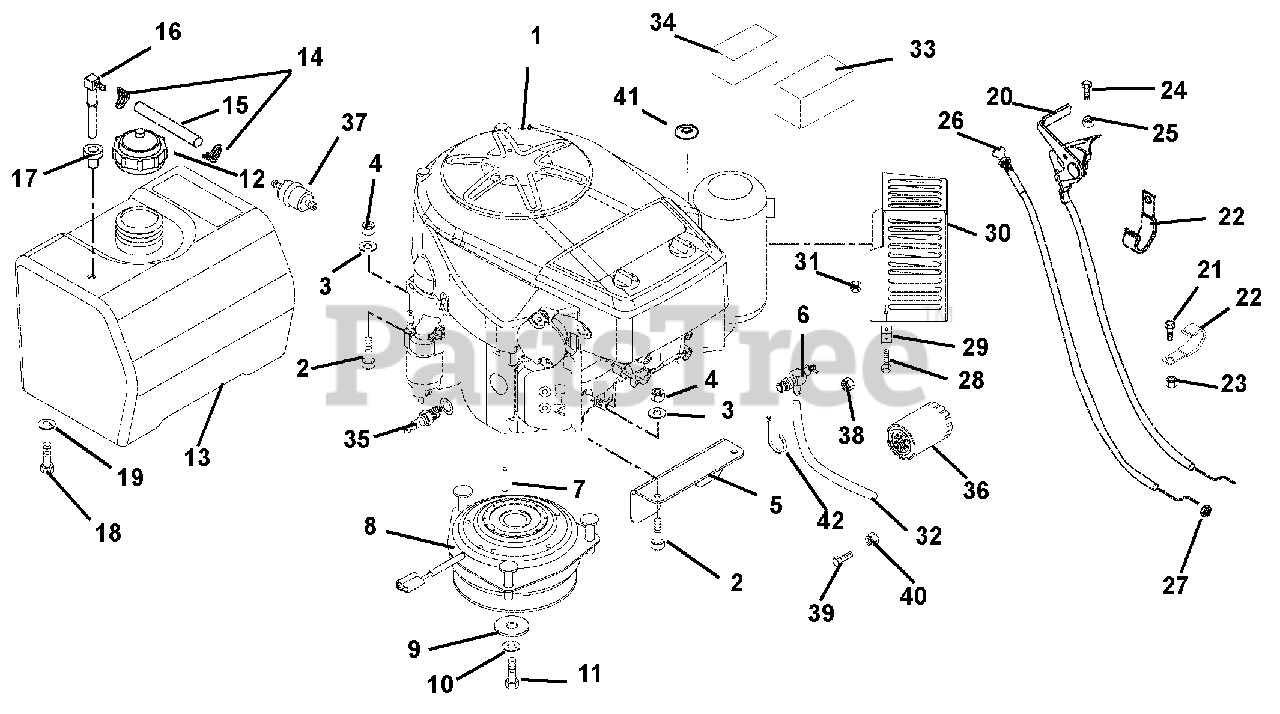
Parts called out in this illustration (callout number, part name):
1	Engine, 17 HP Kawasaki (108, 109, 117)
2	Bolt-Hex .31-18 x 1.75 Grade 5
3	Washer-Locking .31 x .078 Regular
4	Nut-Hex .31-18
5	Bracket, Clutch
6	Valve, Oil Drain
7	Key-Square .25 x 1.25 x 25 SAE 8630 OR SAE 1035
8	Clutch, Electric
9	Washer-Flat-Steel .469 x 2.00 x .25
10	Washer-Locking .44 x .109 Regular
11	Bolt-Hex .44-20 x 3.00 Grade 5
12	Cap, Fuel
13	Tank, Fuel
14	Clamp-Hose Wire .49/.51 x .116
15	Gas Line-Bulk .25 I.D.
16	Fitting, Tank
17	Bushing
18	Bolt-Hex .38-16 x .75 Grade 5
19	Washer-Locking .38 x .094 Regular
20	Cable, Throttle-with Liner (105, 106, 107, 108, 109, 113, 312)
21	Bolt-Hex .31-18 x .75 Grade 5
22	J-Clamp
23	Nut-Locking-Nylon .312-18
24	Screw-Machine 10-24 x .75 Hex Washer Head
25	Nut-Locking-Nylon 10-24 with Insert
26	Control, Choke
27	Nut-Jam .375-24
28	Bolt-Hex .31-18 x .75 Grade 5 (312, 314)
29	Bracket, Muffler Guard (312, 314)
30	Guard, Muffler (312, 314)
31	Nut-Locking-Center .31-18 (312, 314)
32	Tube, Oil Drain
33	Filter, Air Paper (105, 106, 107, 113, 116, 120, 312, 314)
34	Filter, Air Foam (105, 106, 07, 113, 116, 120, 312, 314)
35	Spark Plug
36	Filter, Oil
37	Fuel Filter- Kawasaki
38	Nut-Locking-Center .31-18 (312, 314)
39	Bolt-Hex .38-16 x .75 Grade 5 (312, 314)
40	Nut-Locking-Center .38-16 (312, 314)
41	Washer-Flat-Steel .38 x .87 x .179 (312, 314)
42	Cable Tie
